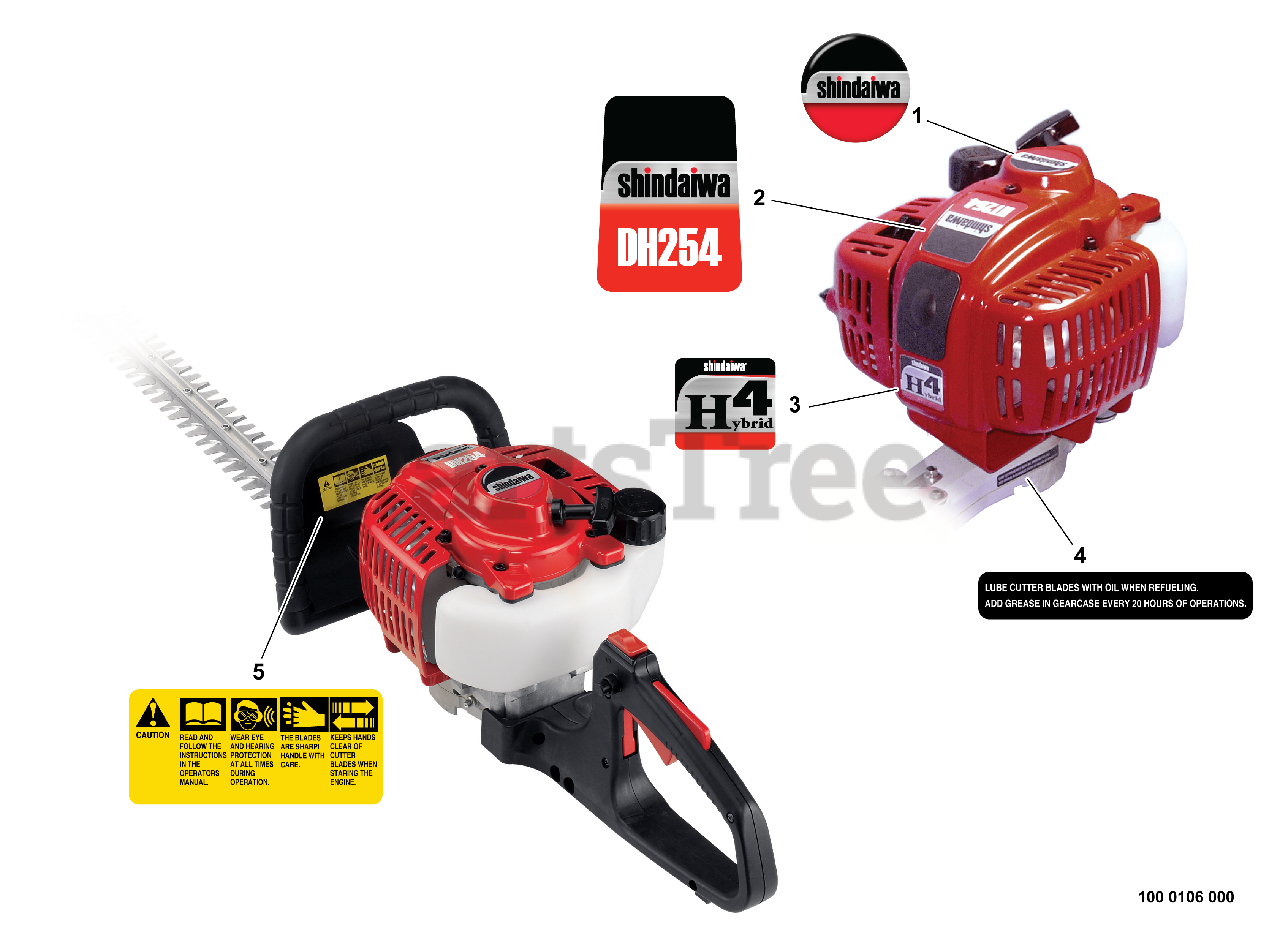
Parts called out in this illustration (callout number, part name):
1	LABEL - SHINDAIWA
2	LABEL - MODEL DH254
3	LABEL - H4
4	LABEL - BLADE LUBRICATION
5	LABEL - CAUTION
